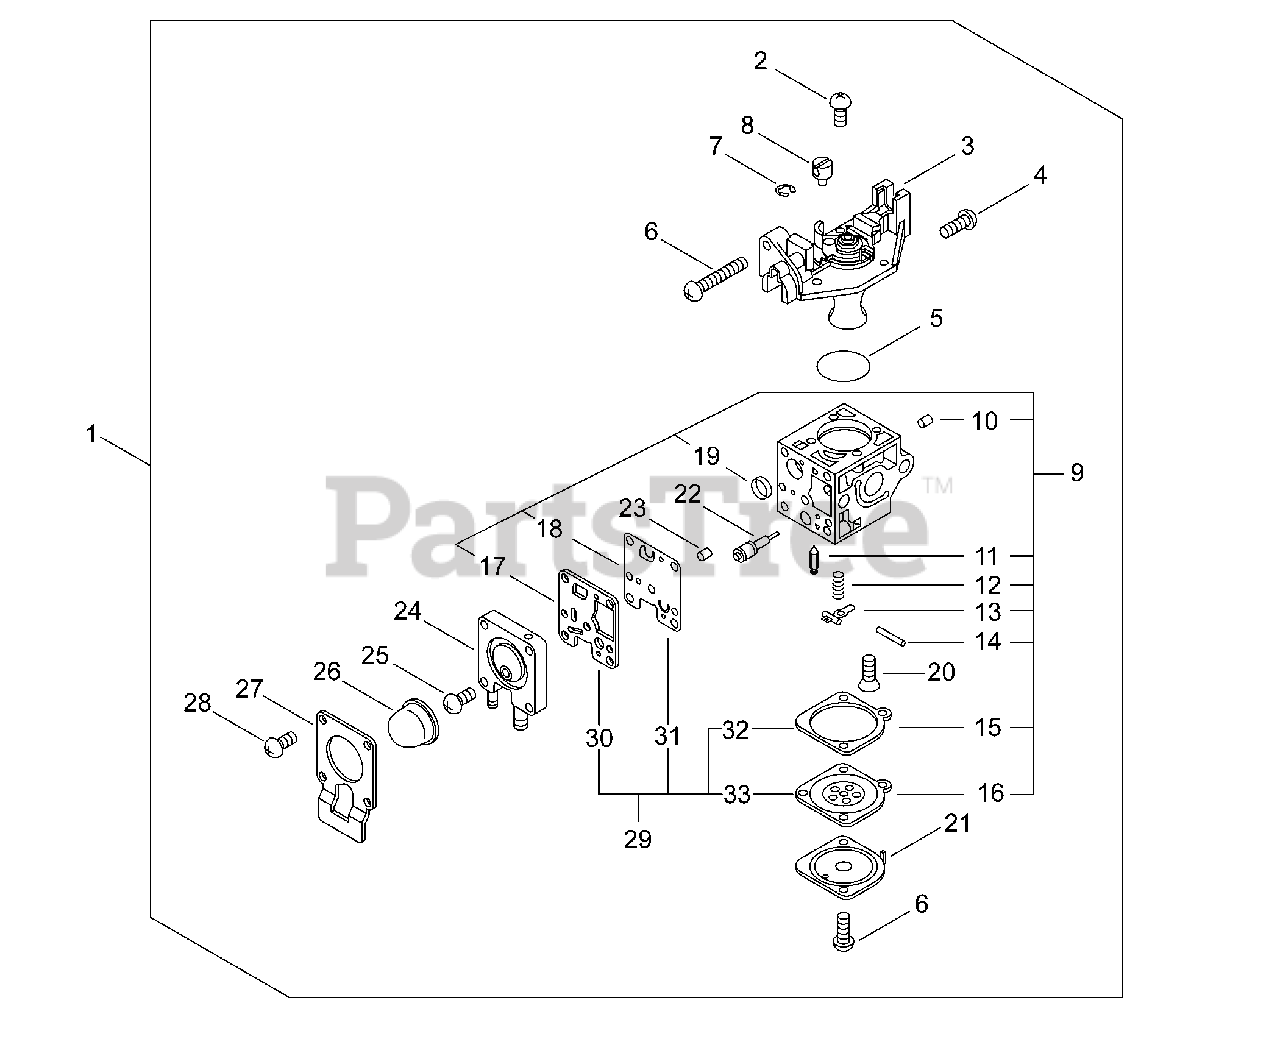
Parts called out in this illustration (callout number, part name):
1	CARBURETOR -- RB-K119
3	COVER ASY, ROTOR
6	SCREW,THROTTLEADJUST
9	REPAIR KIT, CARBURETOR
10	ROLLER, GUIDE
11	VALVE, INLET NEEDLE
12	SPRING, METER. LEVER
13	ARM, VALVE
14	PIN, METERING ARM
15	GASKET, METERING
16	DIAPHRAGM ,METERING
17	GASKET, PUMP
18	DIAPHRAGM, PUMP
19	STRAINER
21	COVER, DIAPHRAGM
22	SCREW,MAINN MIXTURE
23	PLUG, HIGH SPEED NEEDLE
24	BASE, ASY PRIMER
26	PUMP, PRIMER
27	RETAINER
29	DIAPHRAGM/GASKET KIT
30	GASKET, PUMP
31	DIAPHRAGM, PUMP
32	GASKET, METERING
33	DIAPHRAGM ,METERING
